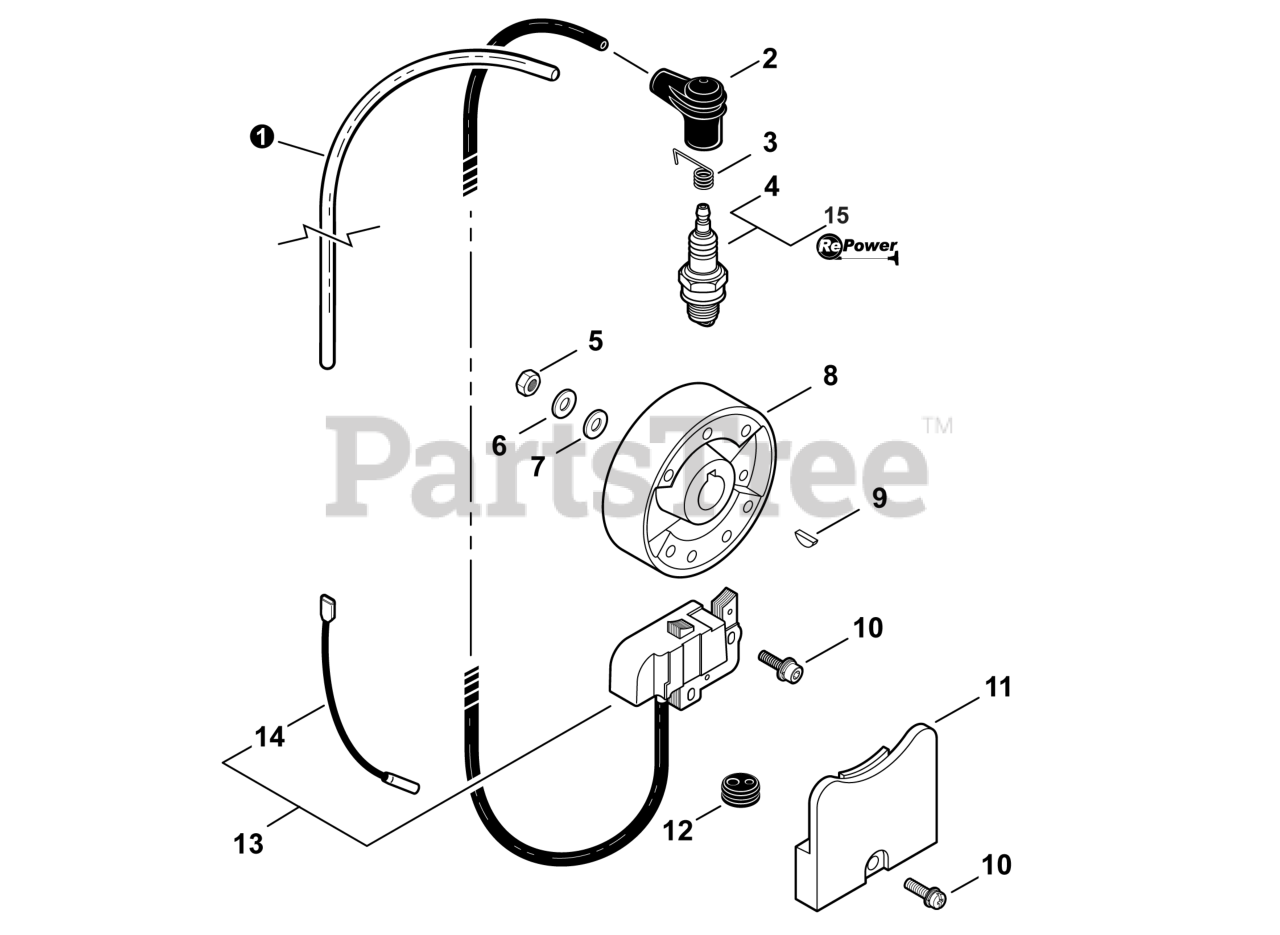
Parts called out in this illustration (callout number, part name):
1	TUBE, VINYL 6.3×8×380
2	CAP, SPARK PLUG
3	TERMINAL, SPARK PLUG
4	SPARK PLUG - BPM8Y
6	WASHER, SPRING 10
7	WASHER, SPRING 10
8	FLYWHEEL
9	KEY, WOODRUFF 3×14
10	BOLT 5×22
11	COVER, DUST
13	COIL ASSY, IGNITION
14	LEAD - IGNITION
15	TUNE-UP KIT - REPOWER
